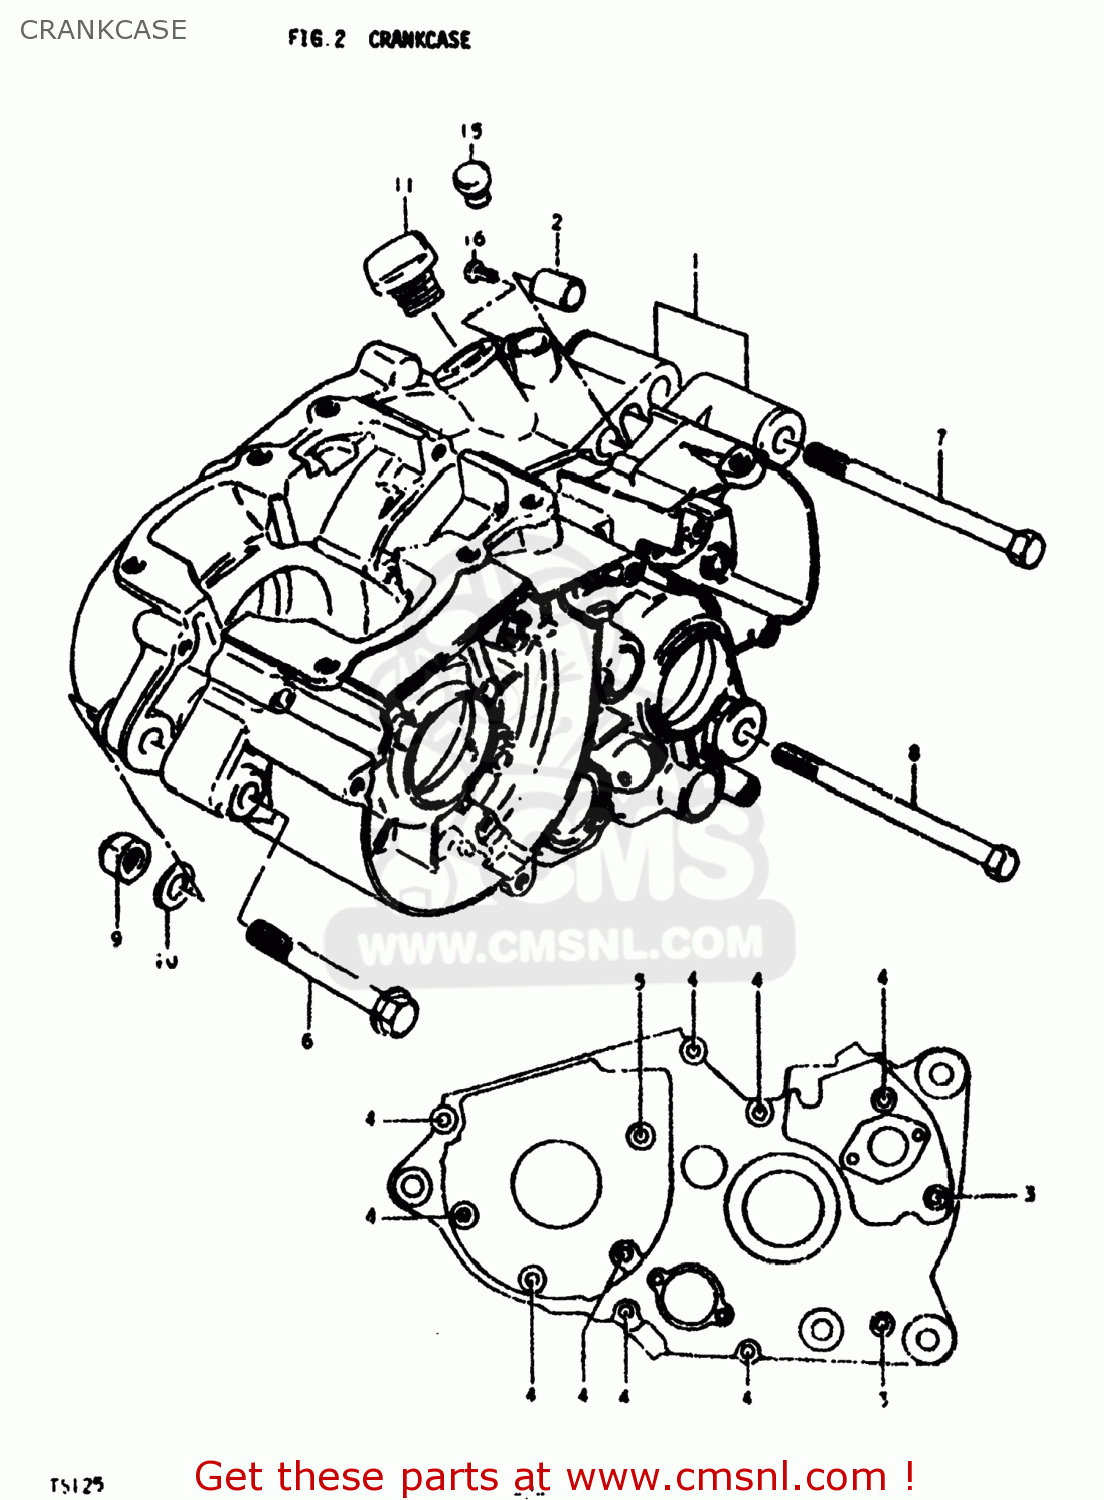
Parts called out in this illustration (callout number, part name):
1	CRANKCASE SET
2	PIN
3	SCREW (6X35)
4	SCREW (6X45)
5	SCREW 6X60
6	BOLT
7	BOLT(10X110)
8	BOLT
9	NUT
10	WASHER
11	PLUG
12	Plug
13	SCREW,6X6
